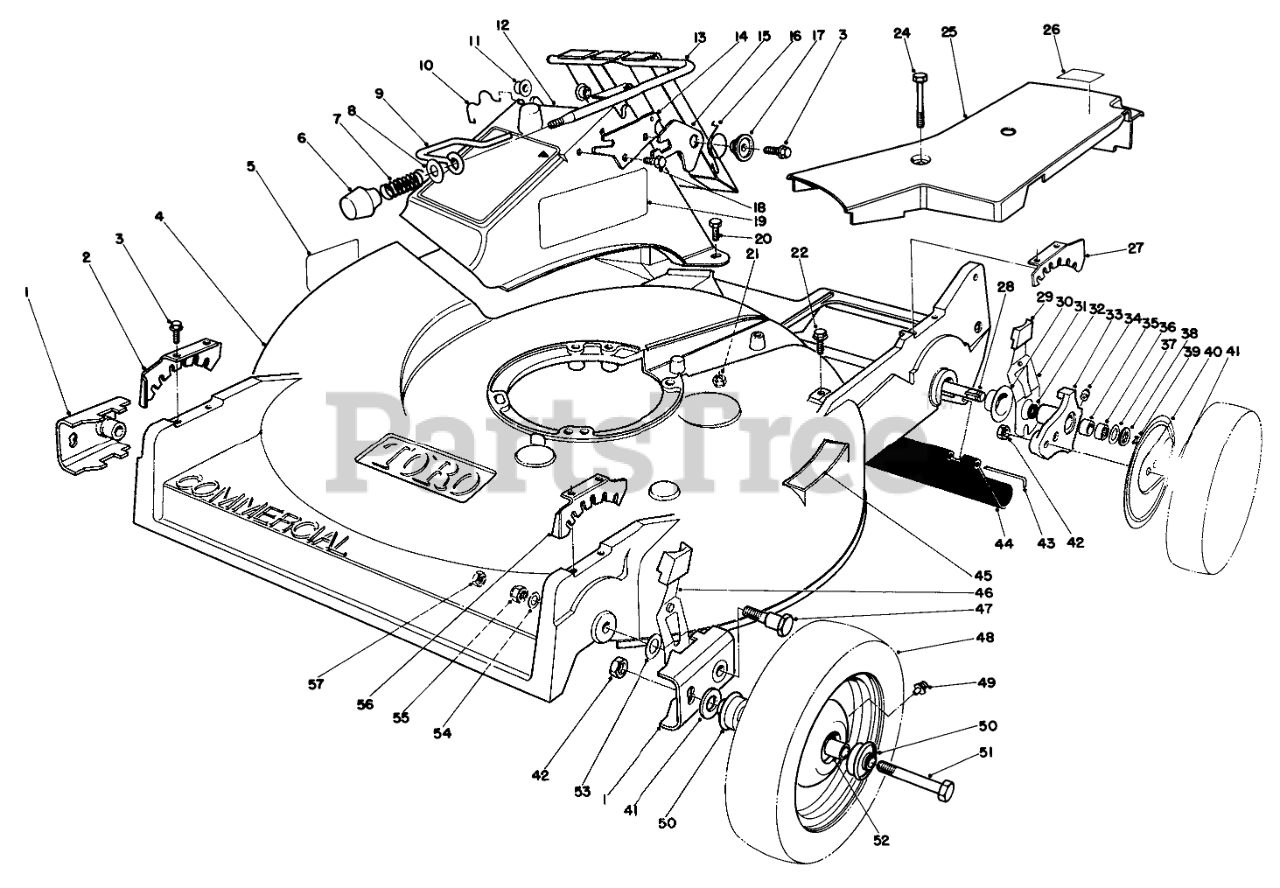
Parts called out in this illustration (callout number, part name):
1	PIVOT ARM ASM
2	RH QUADRANT
3	Screw
4	Housing
5	DECAL-DANGER
7	COMPRESSION SPRING
8	WASHER-FLAT
9	DOOR LATCH
10	DOOR RETAINER
11	BUSHING-NYLON
12	Chute & Door Assembly (Incl. Ref. #3, 6-11 & 13-21)
13	DOOR & HANDLE WA
14	DOOR LATCH PLATE
15	Latch Safety
16	TORSION SPRING
17	DOOR SPACER
18	SCREW-HWH
19	DECAL SAF INST
20	SCREW-HH
21	NUT-LOCK, NI
22	SCREW-HWHTF
24	SCREW-HHFTF
25	Belt-Cover
26	Label-Grease
27	Quadrant-Rear L.H.
28	Output Shaft
29	KNOB-ARM
30	CAP-END
31	SPRING ARM ASM
33	Pivot Arm Assembly (Incl. Ref. #32, 34-36)
34	FITTING-GREASE
35	BUSHING
36	BEARING-NEEDLE
37	THRUST WASHER
38	KEYED WASHER
39	RING-RETAINING
40	WHEEL COVER
41	WHEEL SPACER-HP
42	NUT-LOCK, CONE
43	ROD-SHIELD
44	SHIELD-TRAILING
45	STEP PAD DECAL
46	Spring Arm
47	PIVOT SCREW
48	Wheel & Tire Assembly (Incl. Ref. #49-50 & 52)
49	FITTING-GREASE
50	Bearing-Flanged
51	SCREW-HH
52	Spacer-Wheel Bearing
53	WASHER-PIVOT
54	WASHER-PLAIN
55	NUT-LOCK, NI
56	LH QUADRANT
57	NUT-JAM
